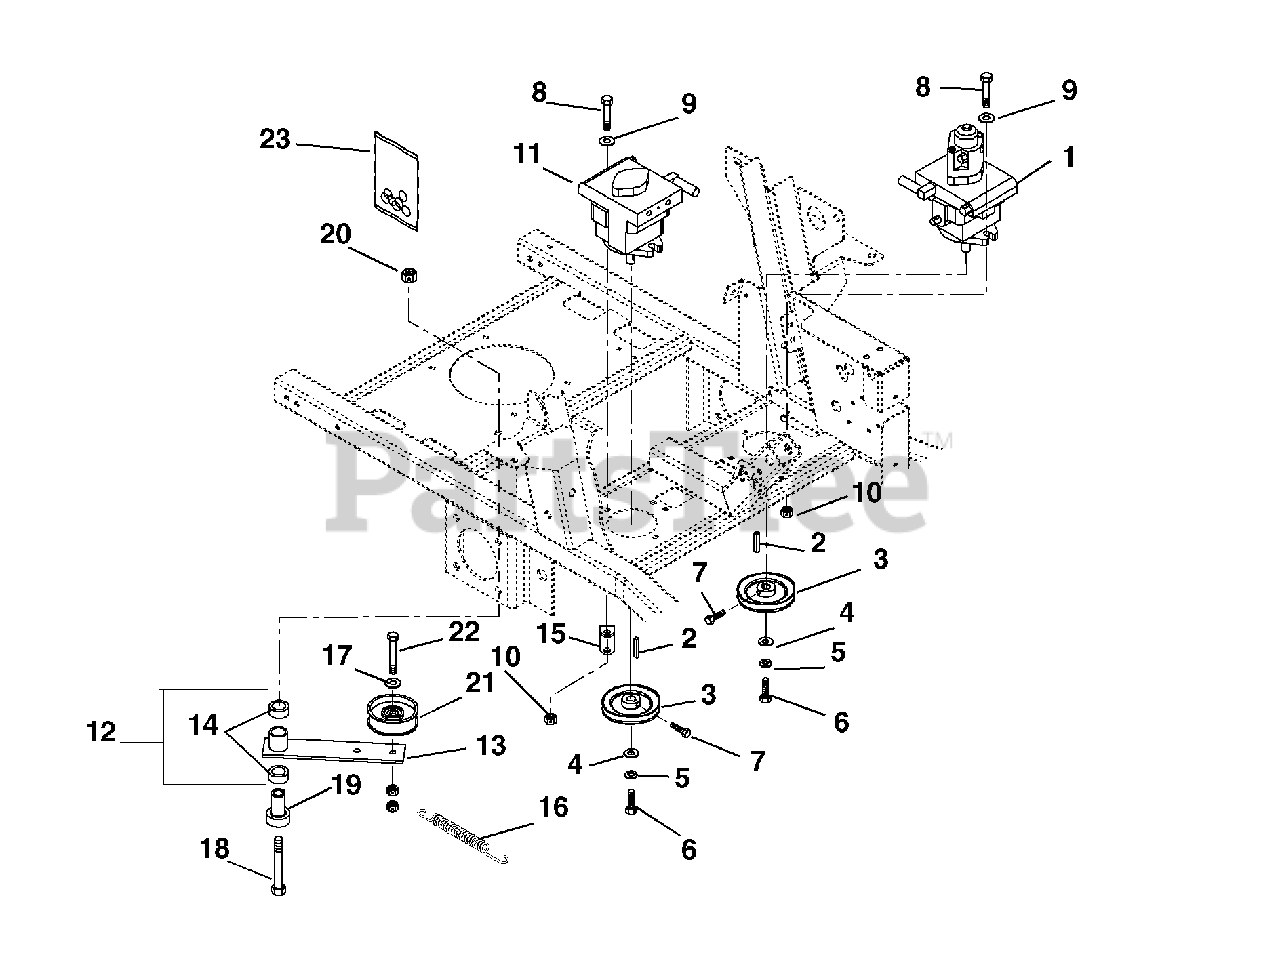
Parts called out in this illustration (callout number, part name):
1	Hydrostat BDP with Auxiliary
2	Key-Straight 5mm x 25mm x 5mm
3	Sheave 4.0 x .199
4	Washer-Flat-Steel .25 x 1.0 x .048
5	Washer-Locking .25 x .062
6	Bolt-Hex M6 x 1.0 x 12
7	Bolt-Hex .25-20 x .50 Grade 5
8	Bolt-Hex .38-16 x 1.25 Grade 5
9	Washer-Flat-Steel .390 x .75 x .125
10	Nut-Locking-Center .38-16
11	Variable-Displace Pump
12	Assembly,Idler Arm Guard Drive
13	Weldment, Idler Arm Ground Drive
14	Bearing, 1.00 x 1.12 x .75
15	Anchor-Spring-Idler
16	Spring-Tension .120 x .845 x 6.500
17	Washer-Flat-Steel .39 x.75 x.125
18	Bolt-Hex .50-13 x 3.50 Grade 5
19	Bearing, Pedestal Powdered Metal
20	Nut-Locking-Center .50-13
21	Assembly-Idler Pulley
22	Bolt-Hex .38-16 x 2.25 Grade 5
23	Kit-Pump Seal
